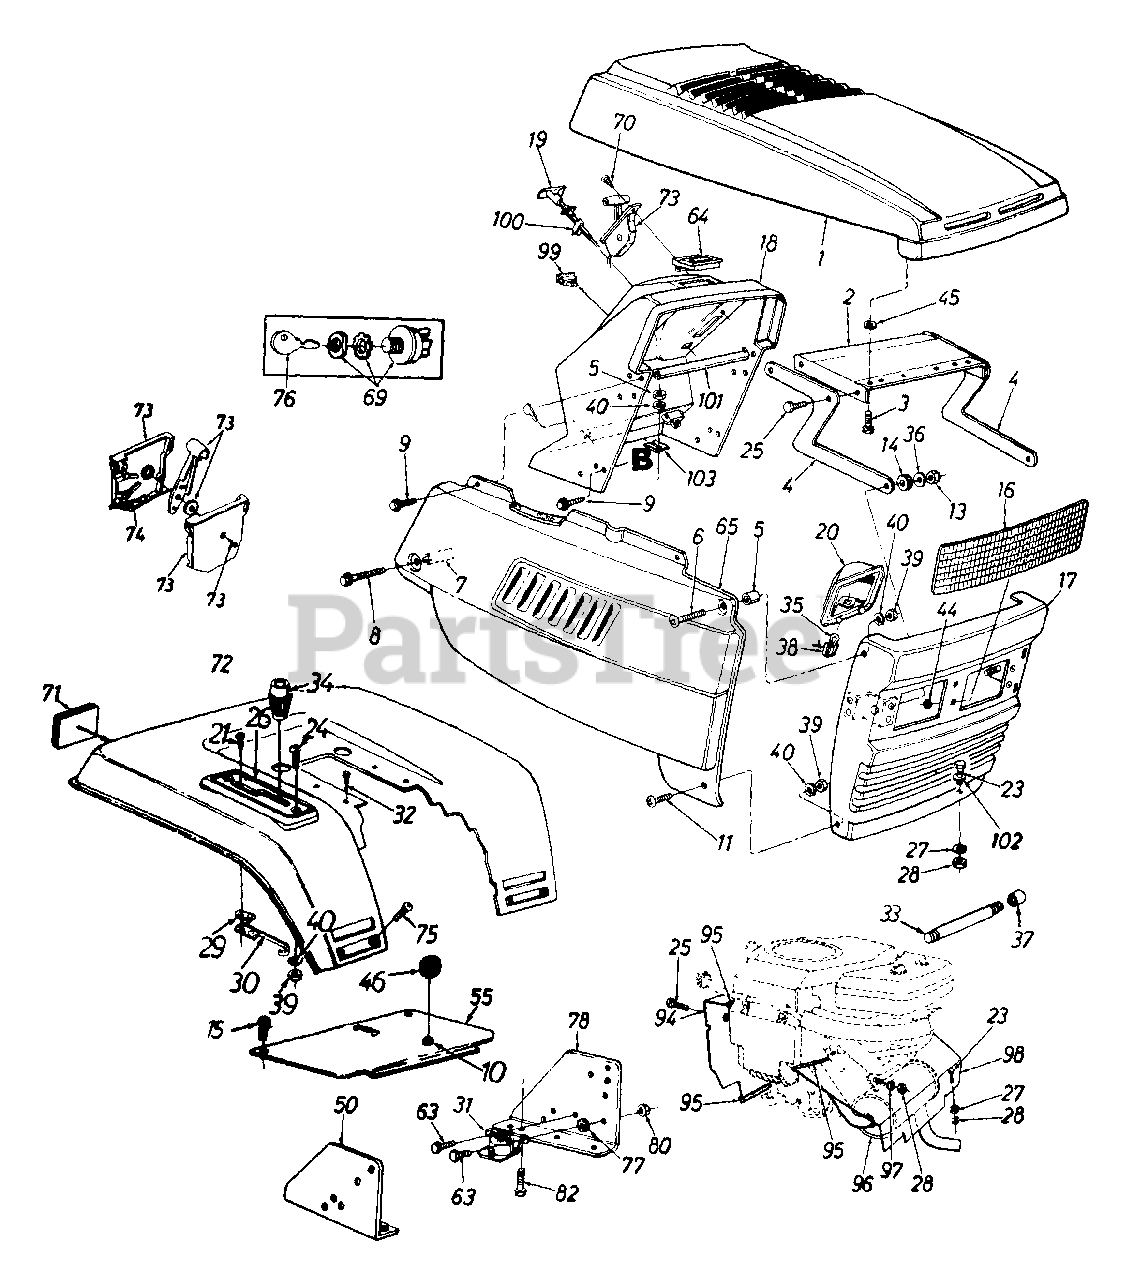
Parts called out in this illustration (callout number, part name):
4	Hood Hinge
5	Spacer .34" I.D. x .437"
6	Truss Hd. Mach. Scr. 1/4-20 Thd.
7	Spacer .26" I.D. x .375"
8	Hex Wash. TT-Tap Scr. 1/4-20 x 1.75" Lg.
9	Hex T-Tap Scr. 1/4-20 x .75" Lg.
10	Snap Bushing
11	Truss Mach. Scr. 1/4-20 x .5" Lg.
13	Hex L-Nut 5/16-18 Thd.
14	Rubber Washer
15	Truss Mach. B-Tap Scr. #10 x .5" Lg.
16	Headlight Lens
19	Choke Control
20	Headlight Housing
21	Hex Wash. Hd. AB-Tap Scr. #8 x .5" Lg.
23	Hex Bolt 5/16-18 x .75" Lg.
24	Truss Mach. Scr. 1/4-20 x 1" Lg.
25	Hex Wash. Hd. Scr. 1/4" x .5" Lg.
26	Index Brkt.
27	L-Wash. 5/16" I.D.
28	Hex Nut 5/16-18 Thd.
29	Insulator Nut Plate
30	Reverse Safety Switch
31	Solenoid
32	Hex Nd. Rolling Scr. 5/16-24 x .75" Lg.
33	Pipe Nipple 3/8-18 Npt.
34	Shift Knob
35	Lamp
36	Bell-Wash..34" I.D. x .87"
37	Pipe Cap 3/8-18 Npt.
38	Socket
39	Hex Nut 1/4-20 Thd.
40	L-Wash. 1/4" I.D.
44	Speed Nut 5/16" I.D.
45	Fl-Wash..406" I.D.
46	Ball Knob
63	Hex Bolt 1/4-20 x 5" Lg.
64	Ammeter
70	Truss Mach. AB-Tap Scr. 010 x .5" Lg.
71	Reflector
74	Throttle Control Wire 35" Lg.
75	Carriage Bolt 1/4-20 x .5" Lg.
76	Key
77	Ext. L-Wash. 1/4" I.D.
94	Engine Baffle
95	Trim Strip 10" Lg.
96	Muffler
97	Spec. L-Wash. 5/16" I.D.
98	Front Heat Shield
99	Light Switch
100	Retainer Clip
101	Dash Support Tube
102	Fl-Wash..344" I.D. x 1" O.D.
103	Dash Panel Fastening Tab
